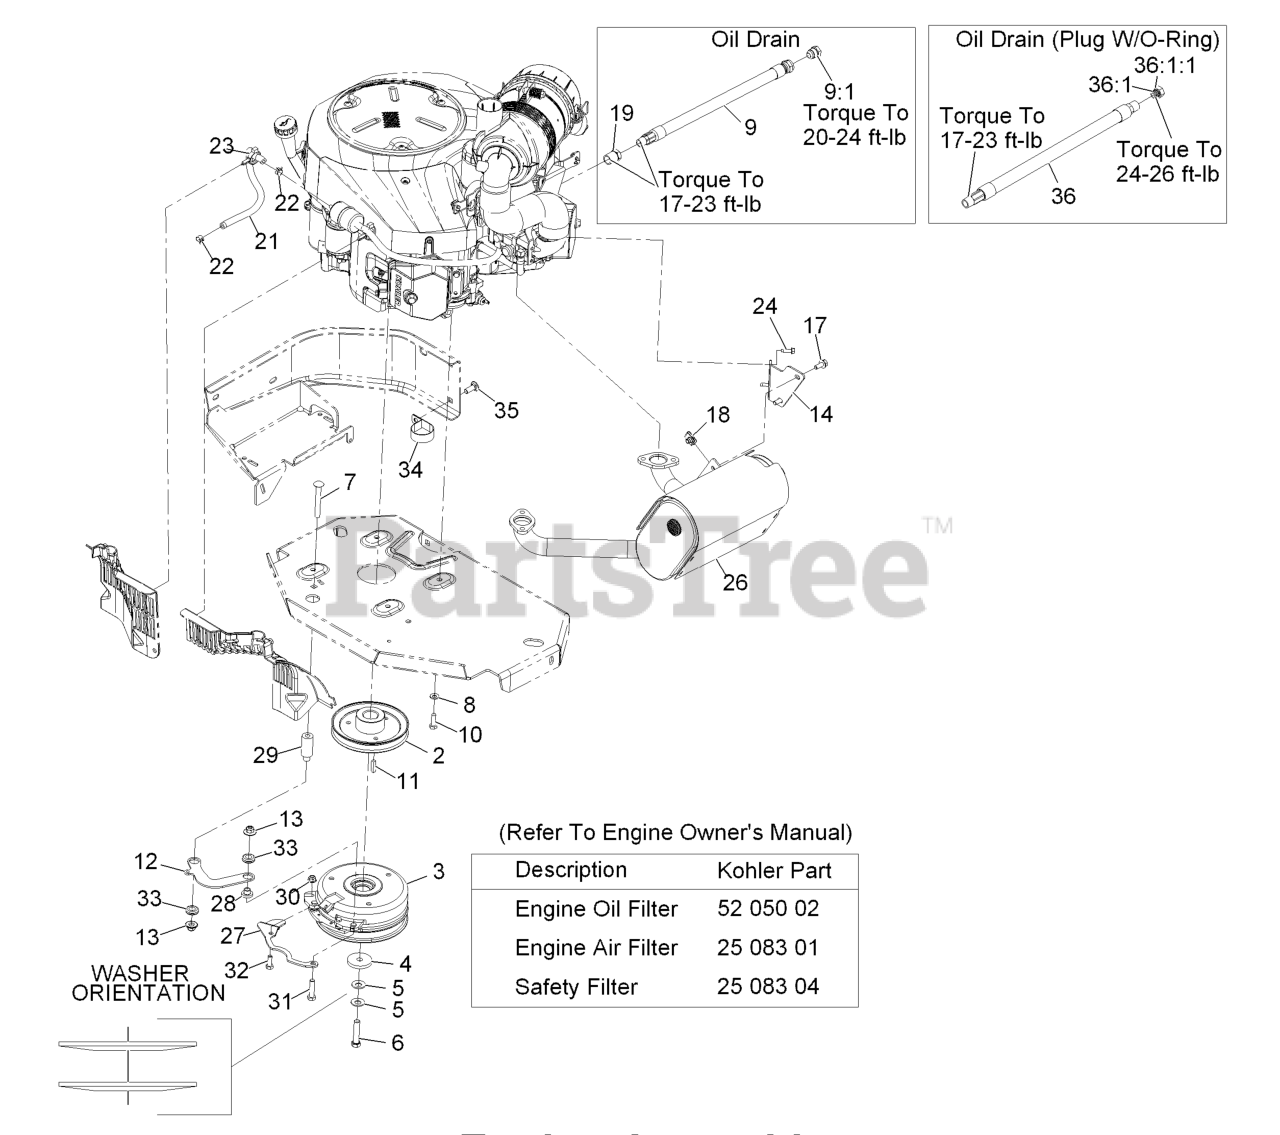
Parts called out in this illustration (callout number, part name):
2	SHEAVE
4	WASHER-CLUTCH
5	WASHER-SPRING
6	SCREW-HH W/LOCTITE
7	SCREW-CARR
8	WASHER-SPRING
10	SCREW-HH
12	LINK-ANCHOR, CLUTCH
13	Nut-Nyloc 3/8-16 Flg
17	SCREW-HHF
19	BUSHING
22	CLAMP-HOSE
23	CLAMP-HOSE
26	MUFFLER
27	BELT-GUIDE
30	NUT-HF, NI
31	SCREW-HH
32	SCREW-HH
33	GROMMET-RUBBER
34	CLAMP-R
35	SCREW-CARR
36	OIL DRAIN HOSE ASM
36:1	PLUG-HH
36:1:1	O-RING
